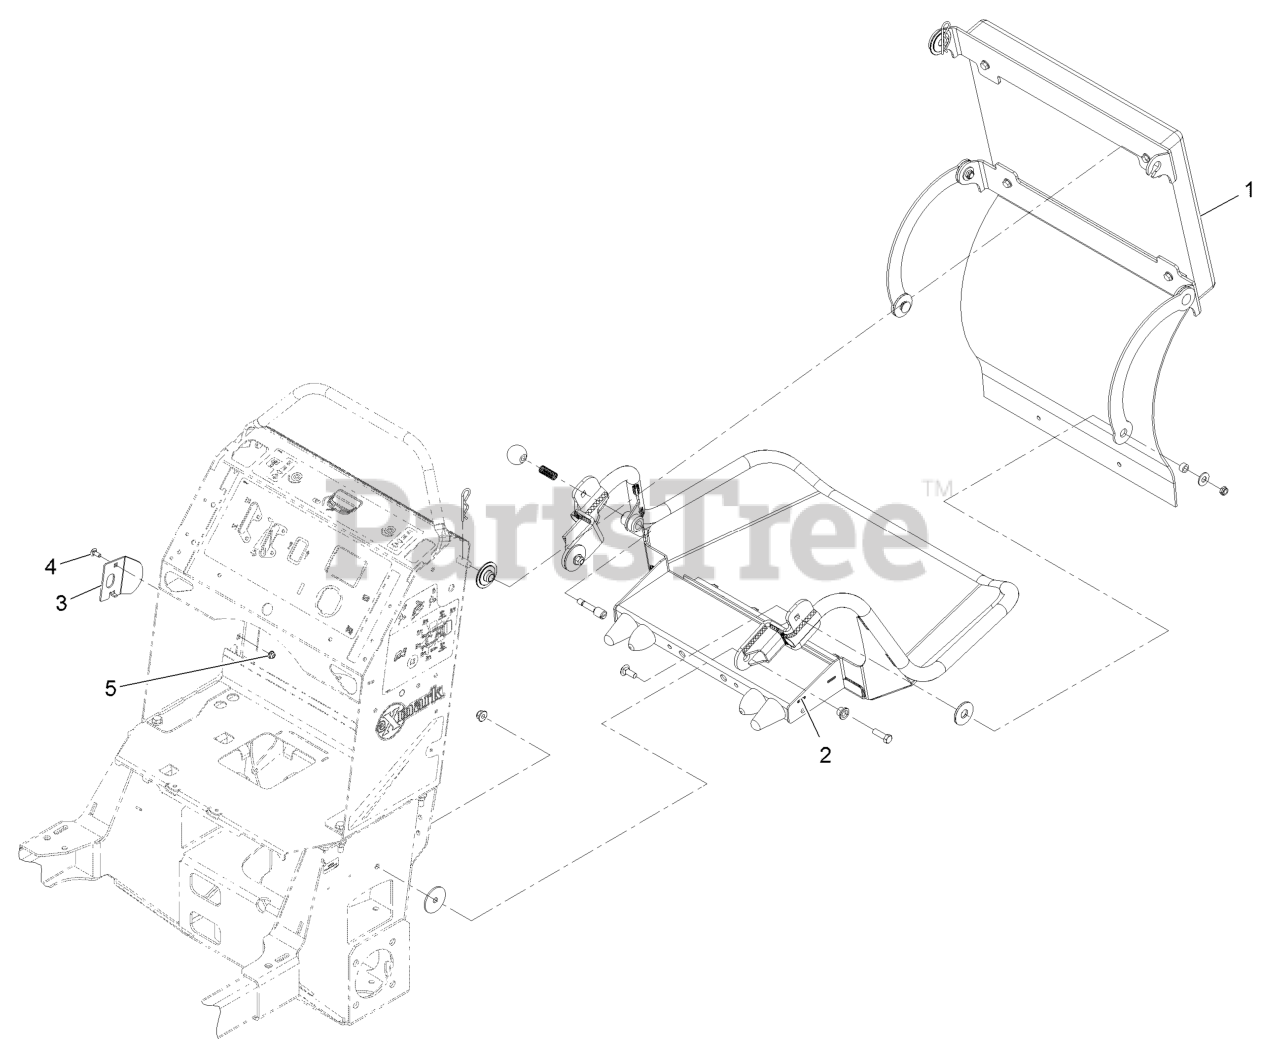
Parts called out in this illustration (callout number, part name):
1	ASM, CUSHION
2	PLATFORM ASM
3	PLATE-STRIKER
4	SCREW-CARR
